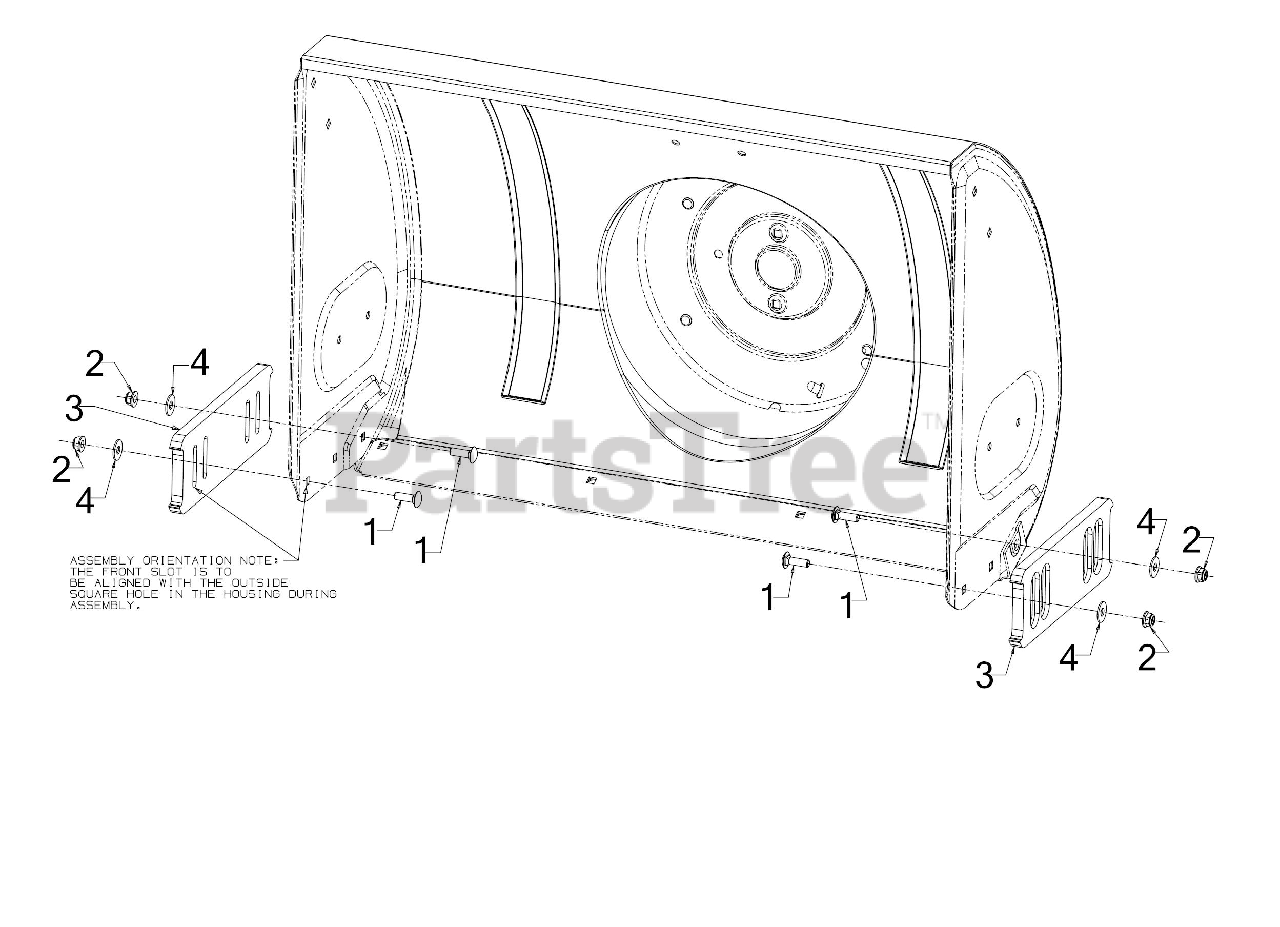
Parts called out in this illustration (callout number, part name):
1	CARRIAGE BOLT 5/16-18 x 1.00
2	FLANGE LOCK NUT 5/16-18
3	SKID SHOE BLUE
4	FLAT WASHER
